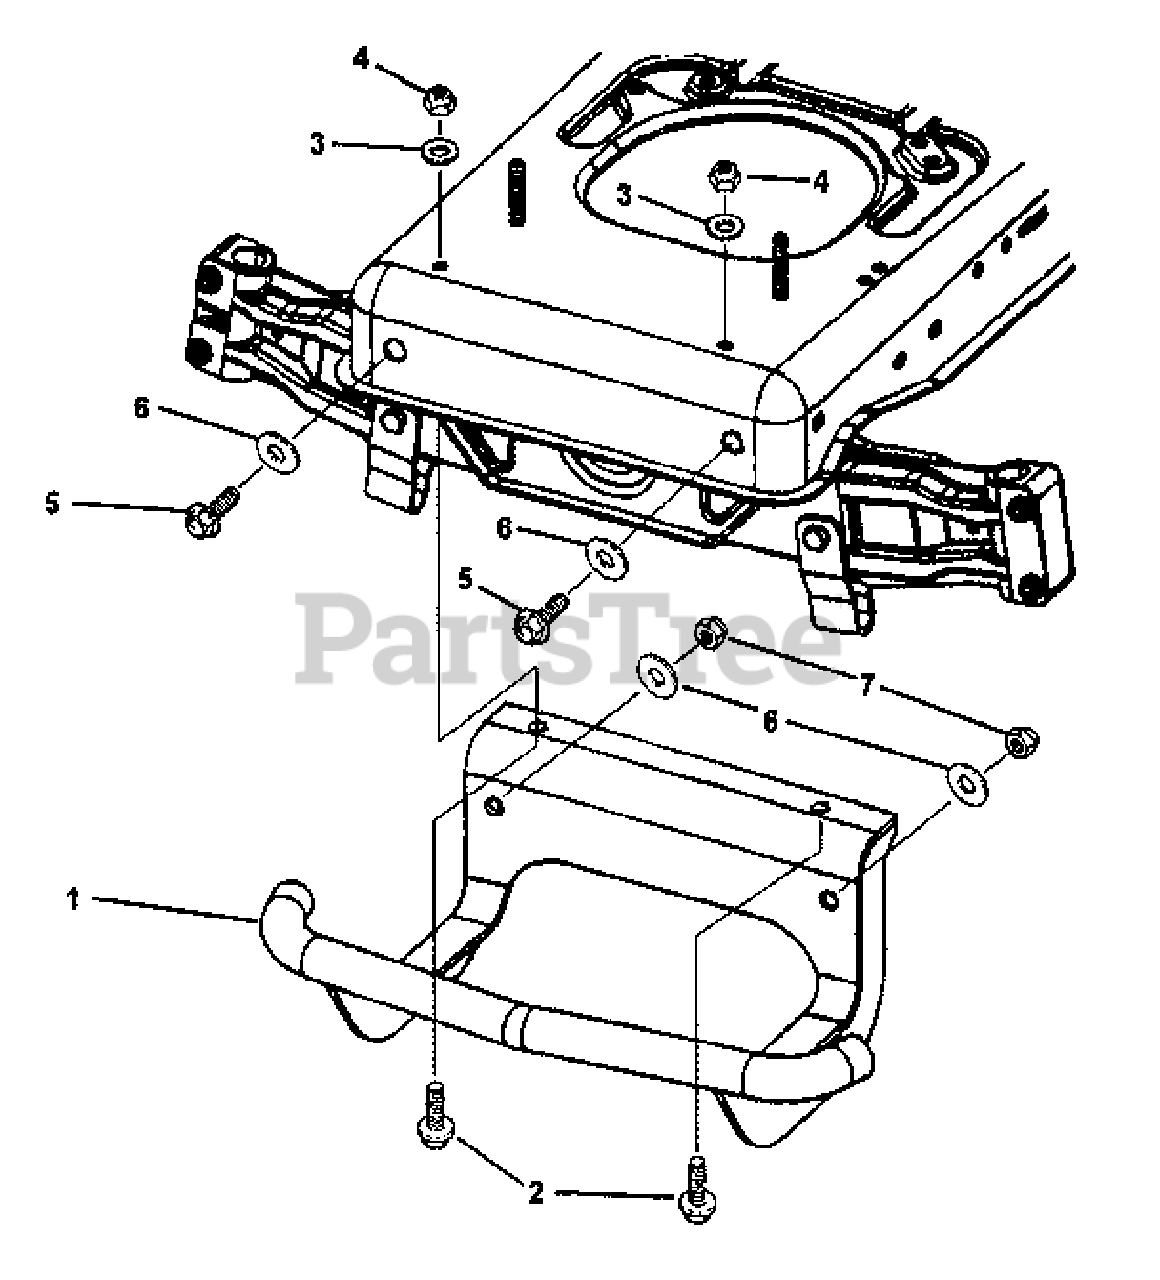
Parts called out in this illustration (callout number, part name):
1	BUMPER
2	BOLT, 5/16-18 x 7/8" Flange Lock
3	WASHER, 5/16" Flat
4	NUT, 5/16-18 Nyloc
5	BOLT, 3/8-16 x 1" Flange Lock Gr. 5
6	WASHER, 7/16" Flat
7	NUT, 3/8-16 Hex Nyloc
